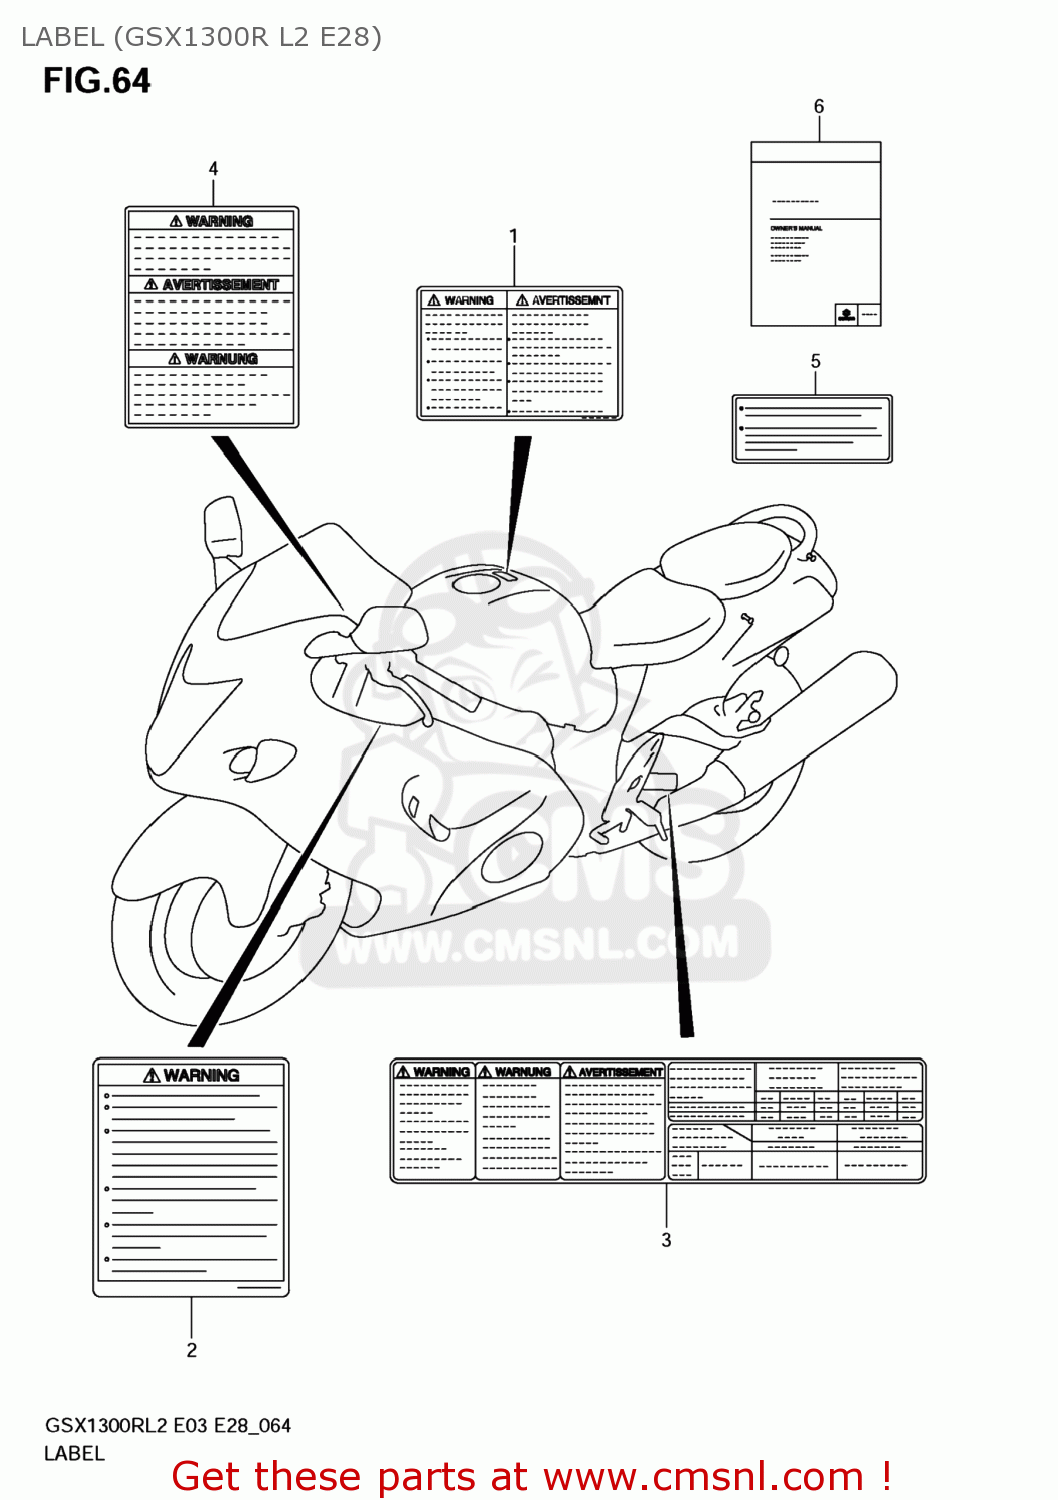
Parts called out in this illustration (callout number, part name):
1	LABEL,GENERAL WARNING
2	LABEL,SCREEN
3	LABEL,TIRE INFORMATION
4	LABEL,WARNING STEERING
5	LABEL,FUEL INFORMATION
6	MANUAL,OWNER'S
